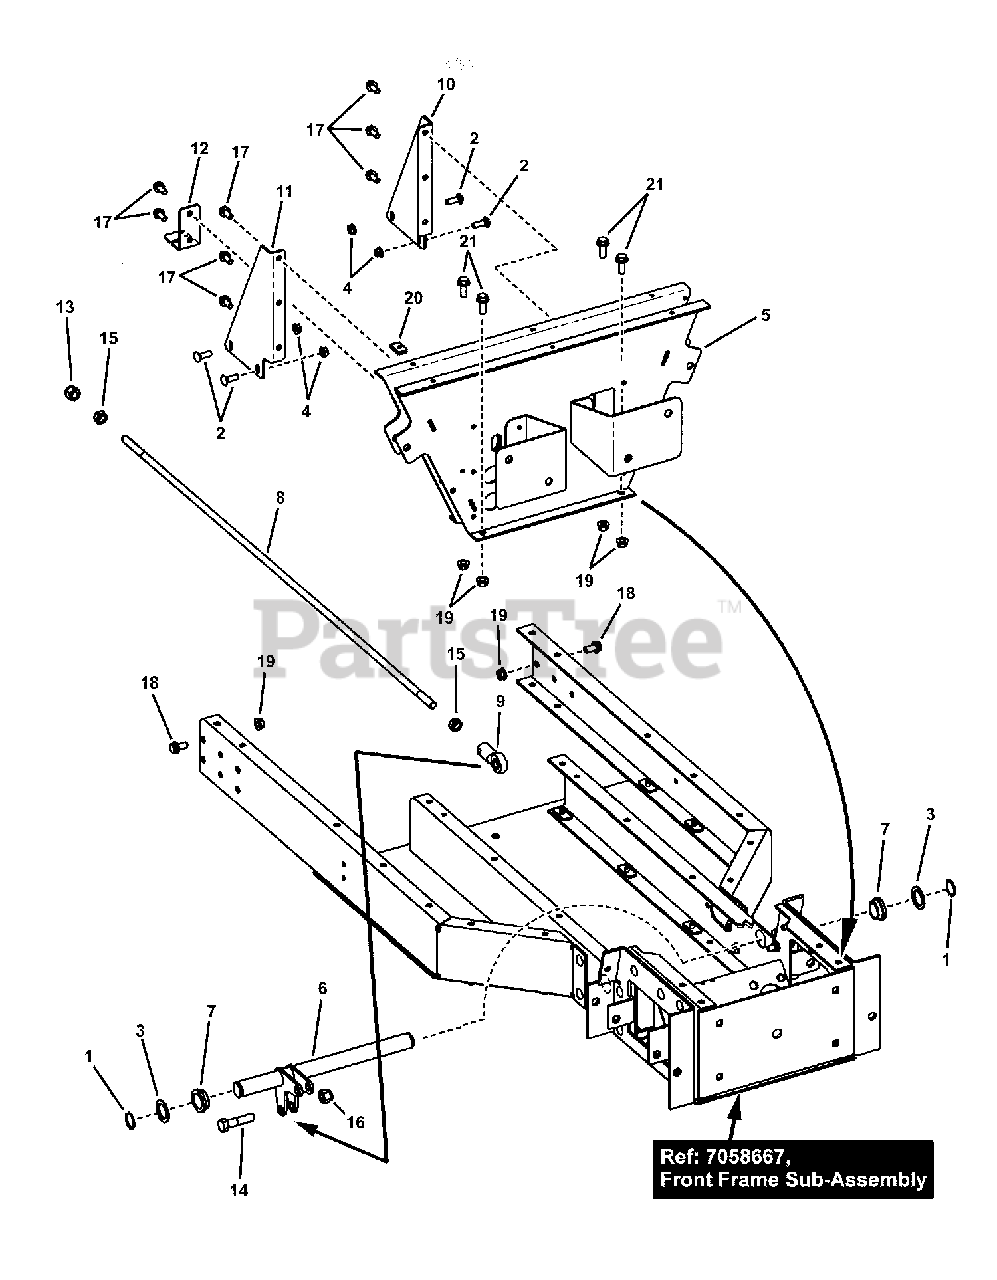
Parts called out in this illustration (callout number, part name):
1	RING, 1.00 Dia. External Retaining
2	BOLT, 5/16-18 x 1" Square Neck Carriage, GR5
3	BUSHING, 14 Ga Machine
4	NUT, 5/16-18 Hex Flange Lock, GR 5
5	WELDMENT, Grill Support
6	WELDMENT, Lower CVT Brake
7	BEARING, 1" I.D.
8	ROD, Lower CVT Brake (1/2-20 thread, both ends)
9	ROD END, Female 1/2-20
10	SUSPENSION GUSSET, LH
11	SUSPENSION GUSSET, RH
12	THROTTLE ANCHOR, Front (black)
13	NUT, 1/2-20 Hex Nyloc
14	SCREW, 1/2-13 x 2" Hex Head Cap, GR 5
15	NUT, 1/2-20 Hex Jam, GR 5 or B
16	NUT, 1/2-13 Hex Nyloc
17	SCREW, 5/16-18 x 3/4" Hex Washer Self-Tap
18	BOLT, 3/8-16 x 3/4" Hex Flange Lock, GR 5
19	NUT, 3/8-16 Hex Flange Lock
20	NUT, 1/4" Tinnerman
21	BOLT, 3/8-16 x 1" Hex Flange Lock, GR 5
